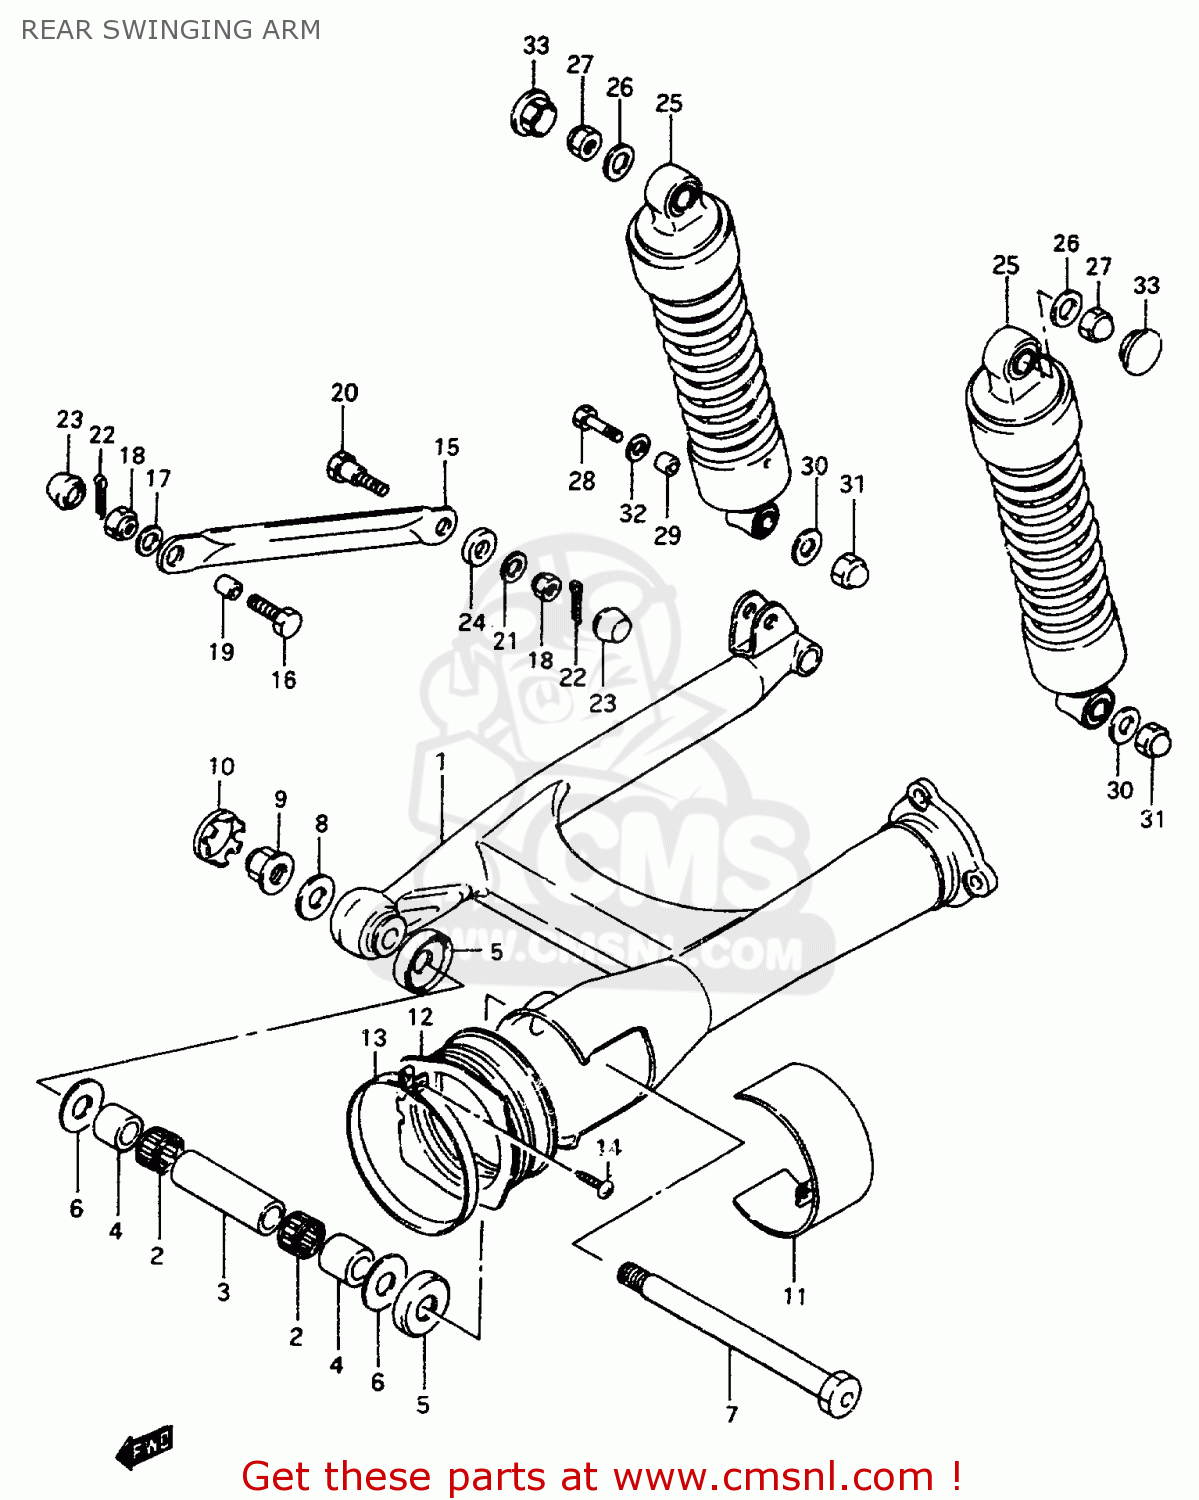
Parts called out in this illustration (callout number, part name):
1	SWING ARM COMP,REAR
2	BEARING(22X29X20)
3	SPACER,RR SWGARM PIVOT
4	SPACER,RR SWGARM PIVOT
5	SEAL,RR SWGARM PIVOT DUST
6	WASHER
7	SAHFT,RR SWGARM PIVOT
8	WASHER(17X30X3)
9	NUT 16MM
10	CAP,RR SWINGING ARM PIVOT,R
11	COVER,REAR SWING ARM PIVOT
12	BOOT,PROPELLER SHAFT
13	CLAMP
14	SCREW
15	TORQUELINK,RR
16	BOLT(10X28)
17	WASHER
18	NUT
19	SPACER
20	BOLT(10X41)
21	WASHER (10X20X2.3)
22	PIN 16X20
23	CAP
24	CUSHION
25	ABSORBER ASSEMBLY,REAR SHOCK
26	WASHER
27	NUT
28	BOLT(10X39)
29	SPACER (10.2X14X20.7)
30	WASHER
31	NUT
32	WASHER 10MM
33	CAP,FRAME HANDLE GRIP
